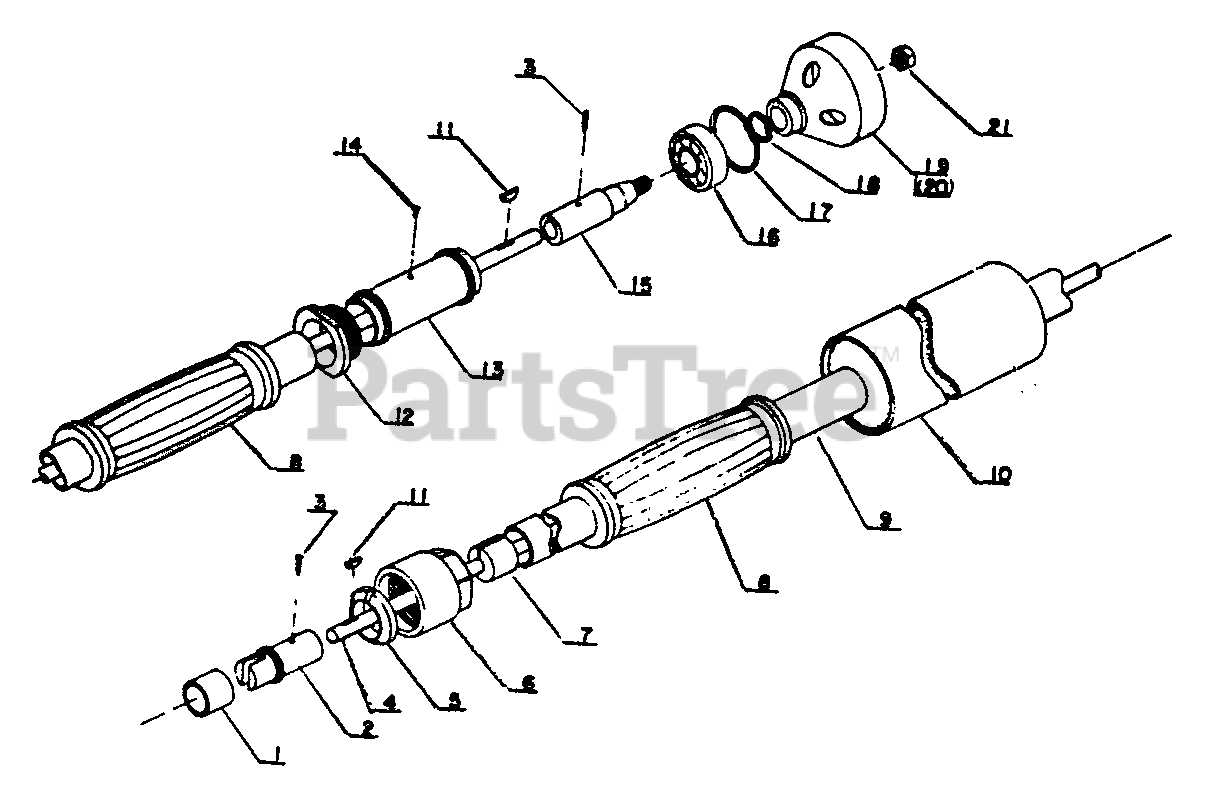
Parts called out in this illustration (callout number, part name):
1	FIX SPACER, DRIVING SHAFT
2	DRIVESHAFT
3	TAPER PIN
4	DRIVESHAFT
6	SLEEVE NUT, OPERATION ROD
7	BEARING, BALL
9	OPERATION ROD
10	CUSHION
12	NUT, OPERATION ROD
13	SLEEVE, OPERATION ROD
14	RIVET
15	DRIVESHAFT
16	BEARING, BALL
17	RING, SNAP Ø32
18	RING, SNAP Ø12
19	CASE, CLUTCH
21	LOCKNUT
